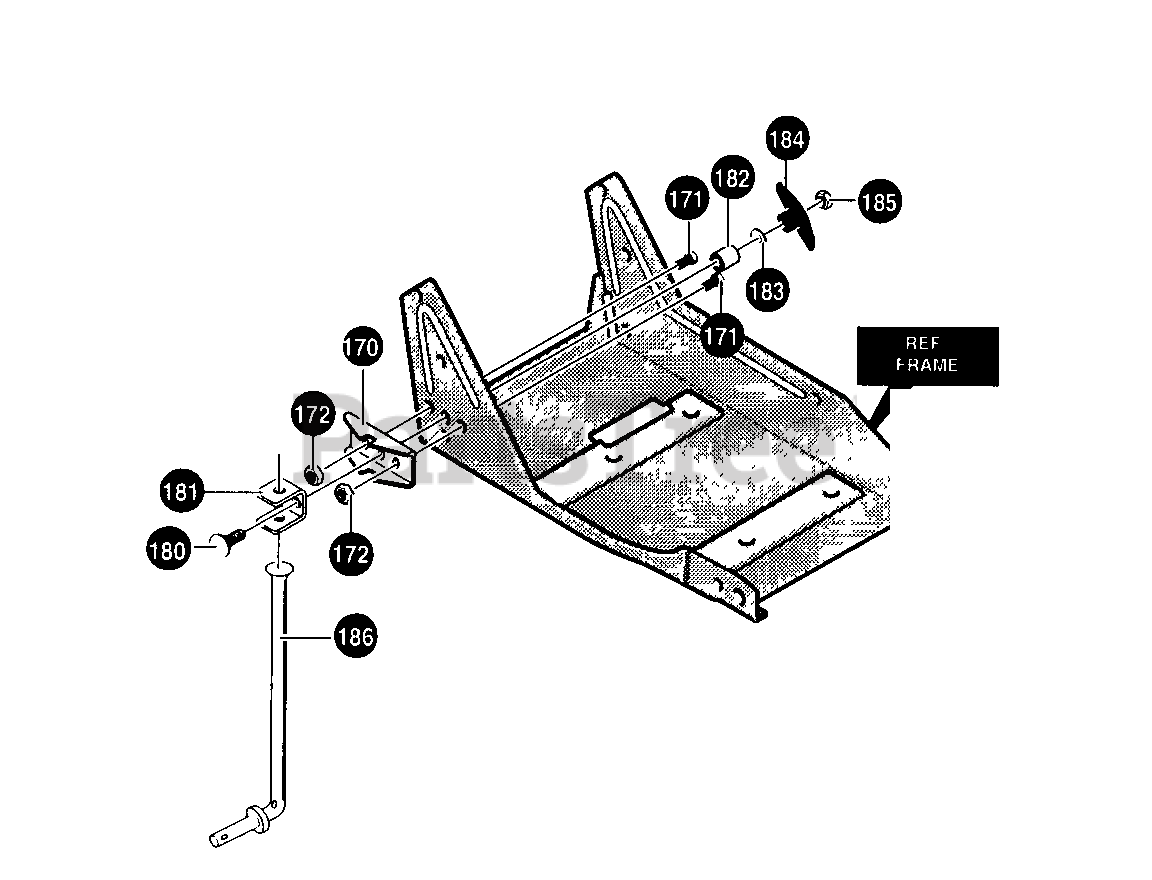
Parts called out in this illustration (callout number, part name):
170	Bracket, Curb Hop Mnt
171	Screw, 5/16-18 x 75
172	Nut, 5/16-18 Reghexctrlk
180	Carr. Bolt, 5/16-18 x 2.00
182	Spacer, Slev .356 x .63 x 1.01
183	Flatwasher .344 x .69 x .065
184	Knob, T
185	Nut, 5/16-18 Reghex
186	Rod, Wheel Support
